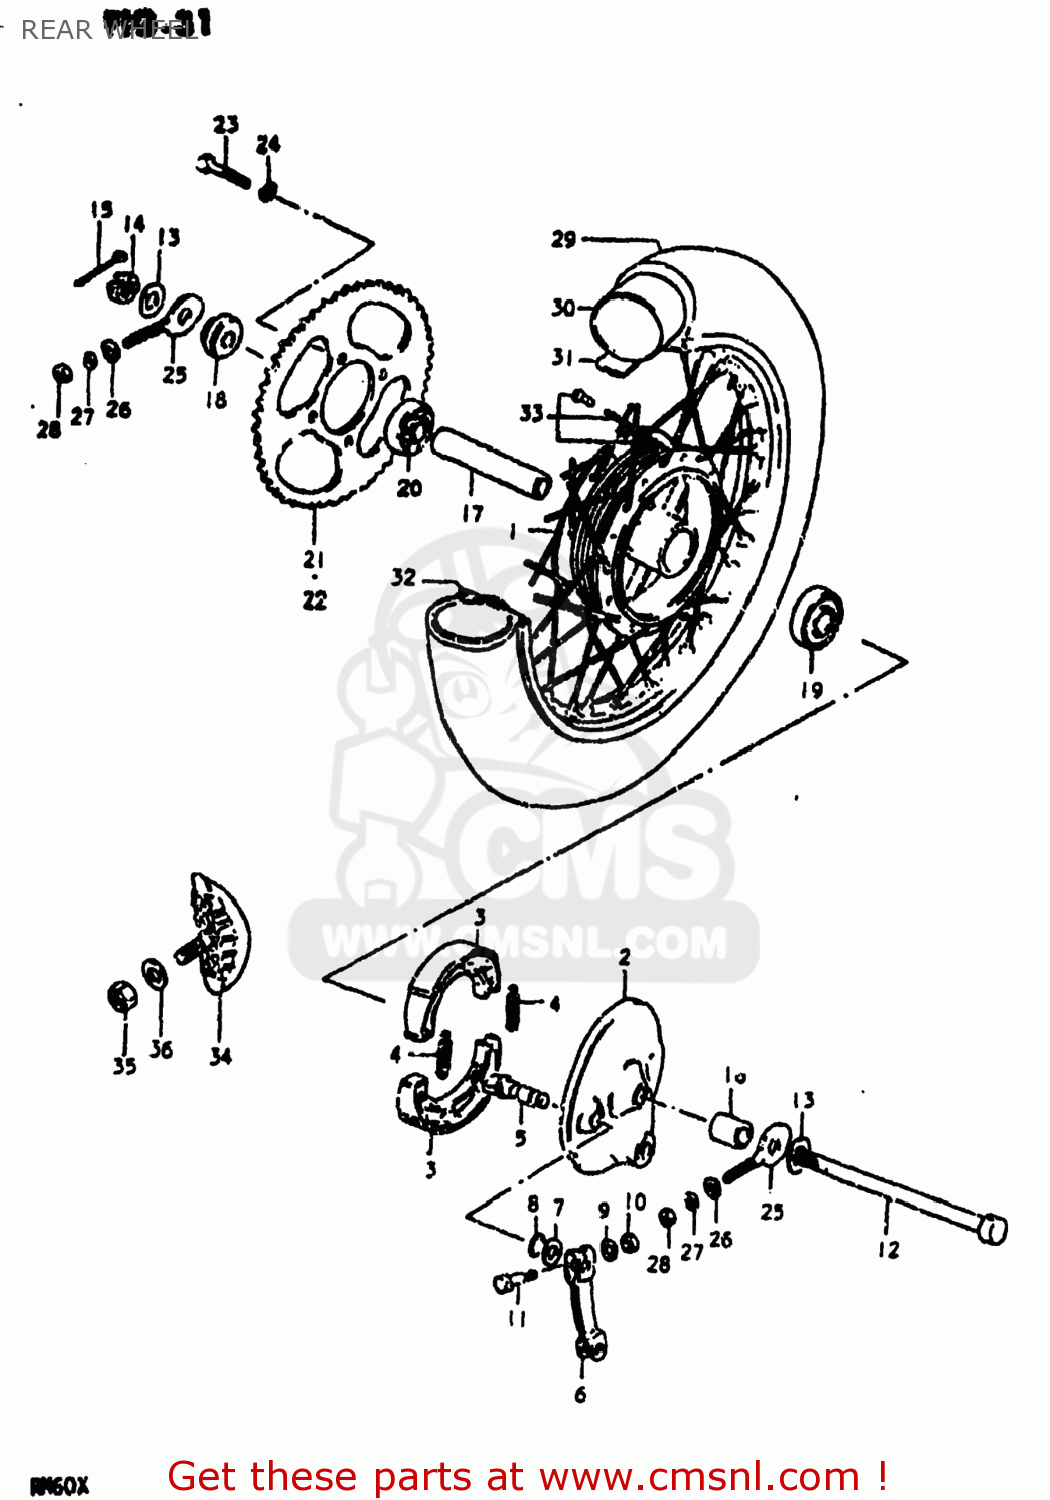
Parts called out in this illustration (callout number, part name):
1	DRUM SET,REAR HUB
2	PANEL,REAR BRAKE ANCHOR
3	SHOE,BRAKE
4	SPRING(L:34)
5	CAM,FRONT BRAKE
6	LEVER,REAR BRAKE CAM
7	WASHER (14.5X22X1.6)
8	O-RING (D:2.4 ID:13.8)
9	WASHER
10	NUT
11	BOLT(6X33)
12	AXLE,REAR
13	WASHER
14	NUT 12MM
15	COTTER PIN
16	SPACER (12.1X22X27)
17	SPACER(12.6X19X91)
18	SPACER,RR AXLE,L
19	BEARING
20	BEARING
21	SPROCKET,RR(NT:42)
22	SPROCKET,REAR (NT:44)
23	BOLT(10X33)
24	LOCK WASHER
25	ADJUSTER,CHAIN,R
26	WASHER
27	LOCK WASHER
28	NUT
29	TIRE
30	TUBE,INNER
31	PROTECTOR,INNER TUBE
32	RIM,REAR WHEEL
33	SPOKE SET,REAR WHEEL
34	STOPPER,BEAD
35	NUT
36	WASHER
